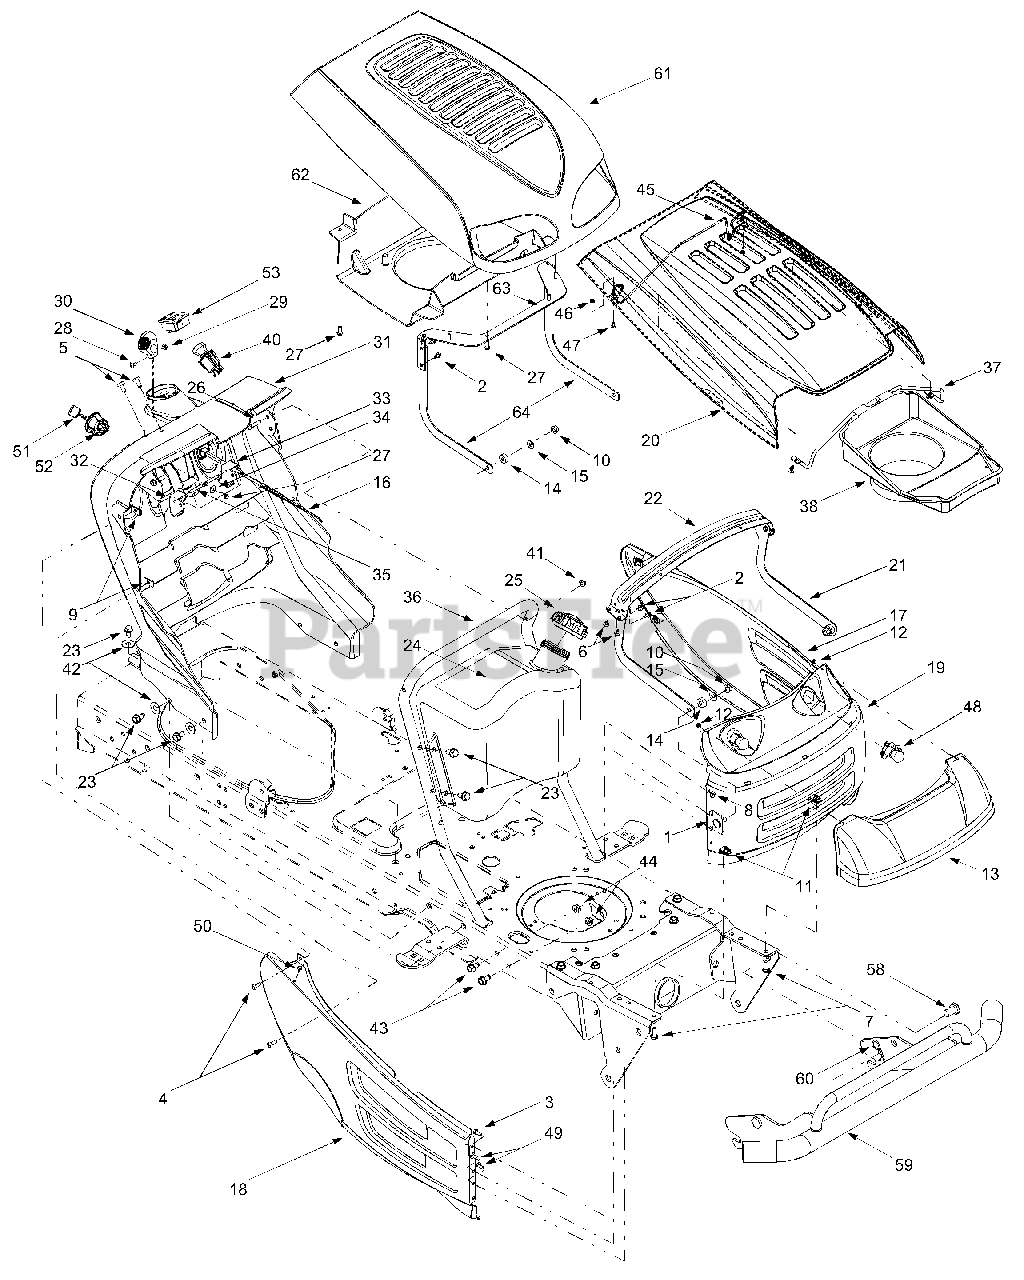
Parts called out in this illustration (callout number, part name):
2	Self-tapping Screw, 1/4-20 x .5
3	Hex Cap Screw, 1/4-20 x .62
4	Phillips Pan Screw, 1/4-20 x .75
5	Truss Phillips Screw, 1/4-20 x .625
6	Screw, #10-16 x .375
7	Hex Cap Screw, 5/16-18 x 1.0
8	Hex Sems Nut, 1/4-20
9	U-type Speed Nut, 1/4-20
10	Flange Lock Nut, 3/8-16
11	U-nut, 5/16-18
12	Retainer Nut, 3/8
13	Headlight Lens (8-style)
14	Rubber Washer, .87 x .33
15	Bell Washer, .401 x .87 x .063
16	Choke Knob/Cable
24	Fuel Tank, Three Gallon
25	Fuel Cap (Fits Either Tank)
26	Self-tapping Screw, 1/4-20 x 1.25
27	Self-tapping Screw, 1/4-15 x .75
28	Truss Phillips Screw, #8-32 x .375
29	Hex Nut, #8-32
30	Throttle Control Knob
31	Dash Panel (Models w/ Electric PTO)
32	Cruise Control Button
33	Parking Brake Button
34	Flat Washer, 9/32 x 1/2 x 1/16
35	Brake/Cruise Pivot Rod
38	Hood Plenum
40	Electric PTO Switch
41	Hex Flange Lock Nut, 1/4-20
42	Flat Washer, .349 x 1.0 x .063
43	Screw, 5/16-18 x .875 (Grade 5)
44	Hex Nut, 5/16-18
45	Hood Latch
46	Hex Sems Nut, #10-32
47	Machine Screw, #10-24
48	Headlight Assembly
49	Hex Index Washer Screw, 1/4-14 x .0625
50	Rubber Bumper
51	Ignition Key w/ plastic cover
52	Ignition Switch
53	Systems Indicator Monitor w/ Hour Meter
58	Clevis Pin, .50 x .78
59	Bumper Assembly
60	Internal Cotter Pin
61	Hood, Red (7-Style)
62	Hood Plenum, 7-Style (w/o Intake Bellow)
